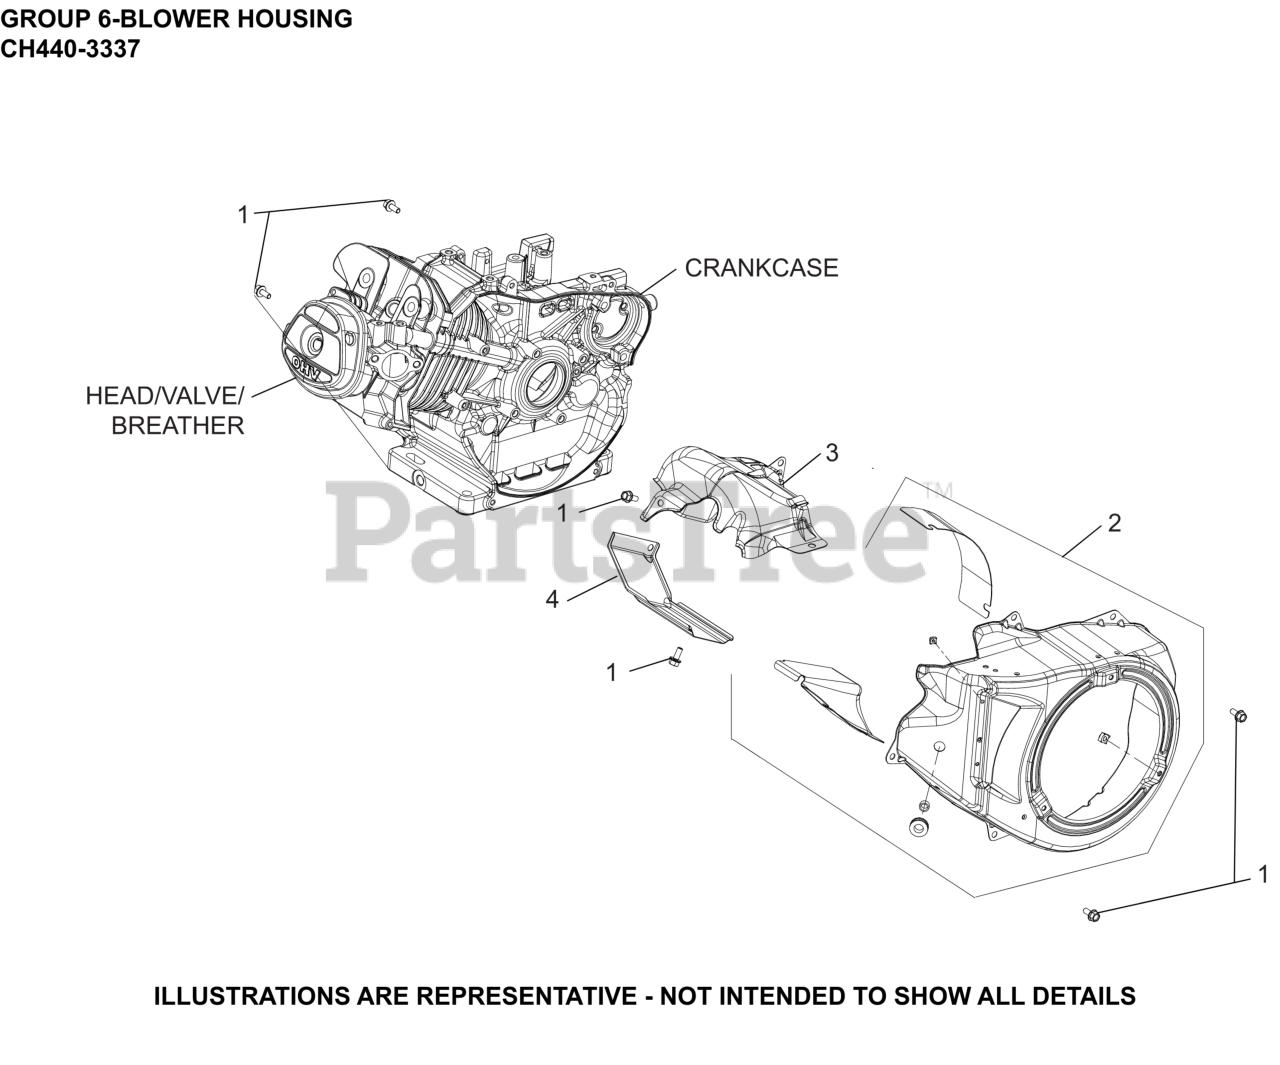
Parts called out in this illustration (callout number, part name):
1	SCREW, HEX FLANGE (M6)-USE 25 086 433-S
2	HOUSING, BLOWER ASSEMBLY
3	SHIELD, UPPER HEAT
4	SHIELD, CYLINDER HEAD
